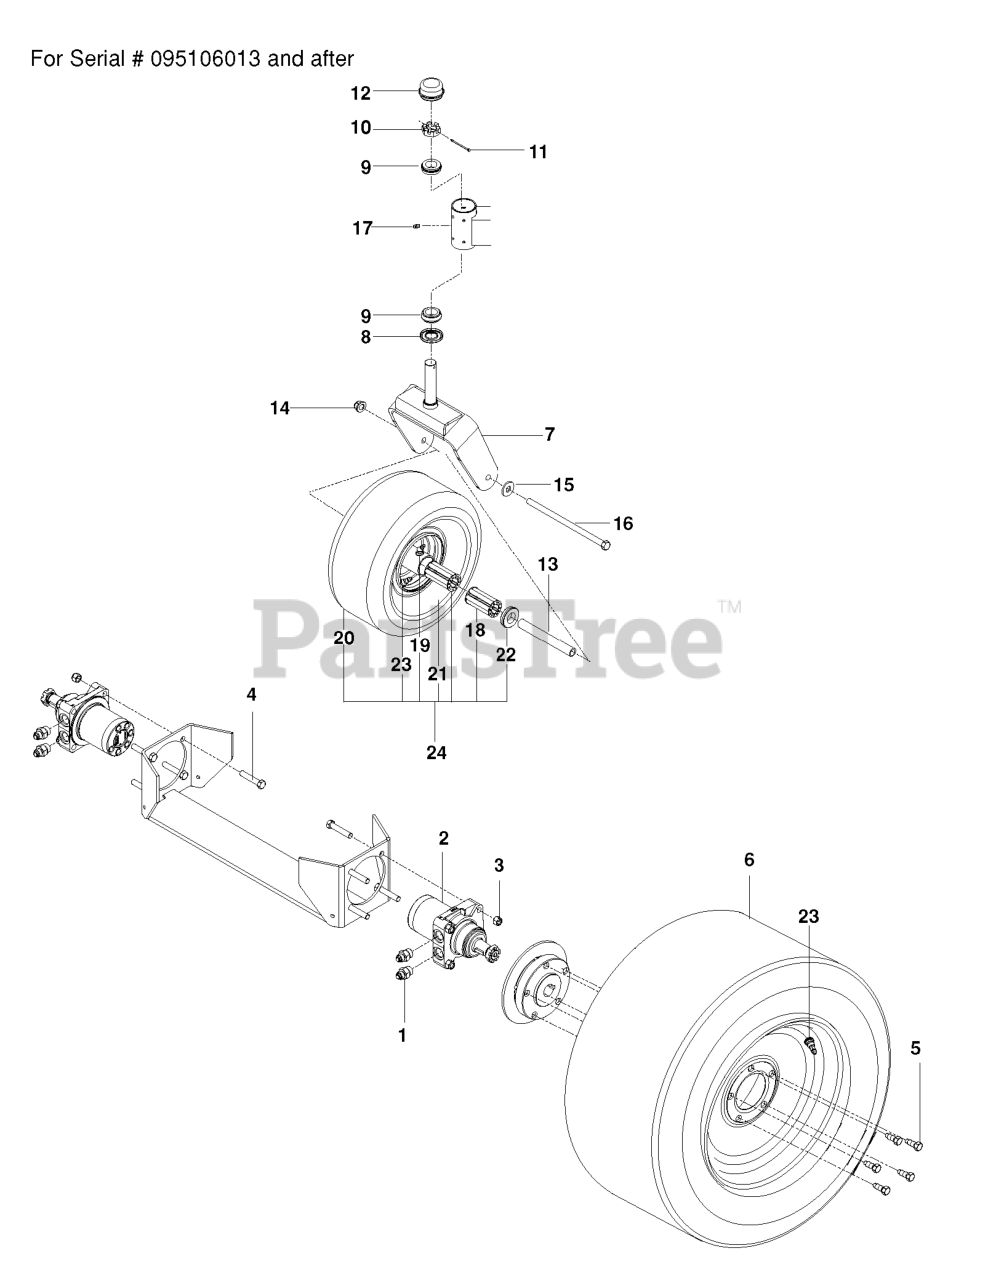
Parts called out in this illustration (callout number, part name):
1	CONNECTOR, STRAIGHT
2	WHEEL MOTOR, TJ
3	NUT 1/2-13 HEX NYLOC ZD
4	HCS 1/2C X 2 3/4
6	WHEEL.R.TS.23X10.5-12.C.MS
7	YOKE.CASTER.ORANGE
9	TAPERED ROLLER BRG
10	NUT 1"C HEX SLOTTED
11	COTTER PIN 1/8 X 2
12	GREASE CAP
13	SPACER, PIVOT
14	NUT, 1/2-13 HEX FLG NYLOC ZD
15	WASH USS FLAT 1/2
16	HEX SCREW 1/2-13 X 9.5 GR5
18	ROLLER BEARING-CAGED 3 1/4'
19	ZERK
20	TIRE.13X6.50-6.4.PLY
21	WHEEL.6X4.50.CASTER.SILVER
22	BEARING RETAINER
23	VALVE STEM TR-412
24	TIRE.ASSEM.CASTER.13X6.5-6.SIL
